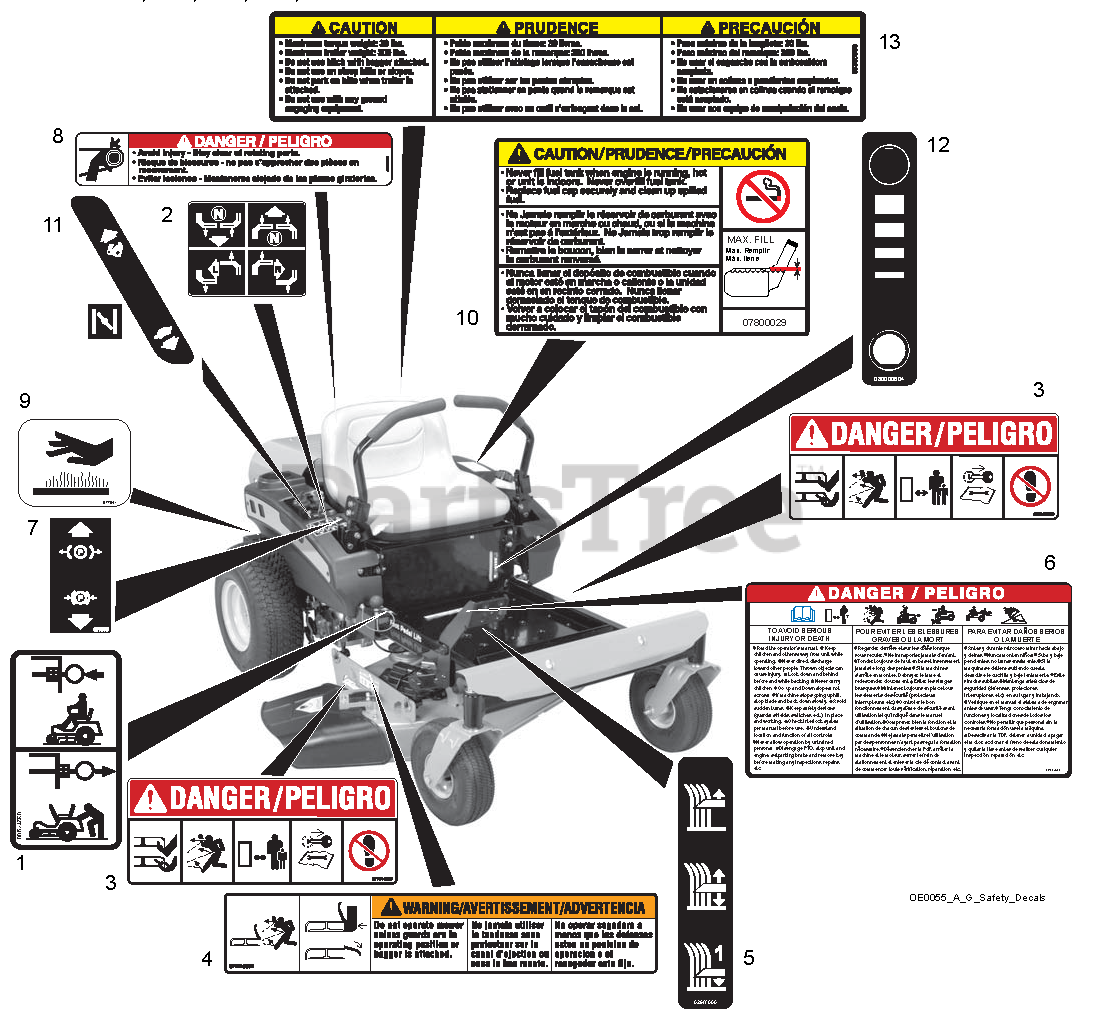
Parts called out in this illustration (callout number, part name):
1	DECAL, TRANSMISSION DISCONNECT
2	DECAL, INSTRUCTIONAL-STEERING
3	DECAL, MOWER PAN DANGER
4	DECAL, WARNING
5	DECAL, CUT HEIGHT
6	DECAL, DANGER BILINGUAL
7	DECAL, PARKING BRAKE LEVER
8	DECAL- DANGER
9	DECAL, HOT SURFACE
10	DECAL-FUEL, WARNING
11	DECAL, SPEED CONTROL
12	DECAL, FUEL LEVEL
13	DECAL, TRAILER HITCH
